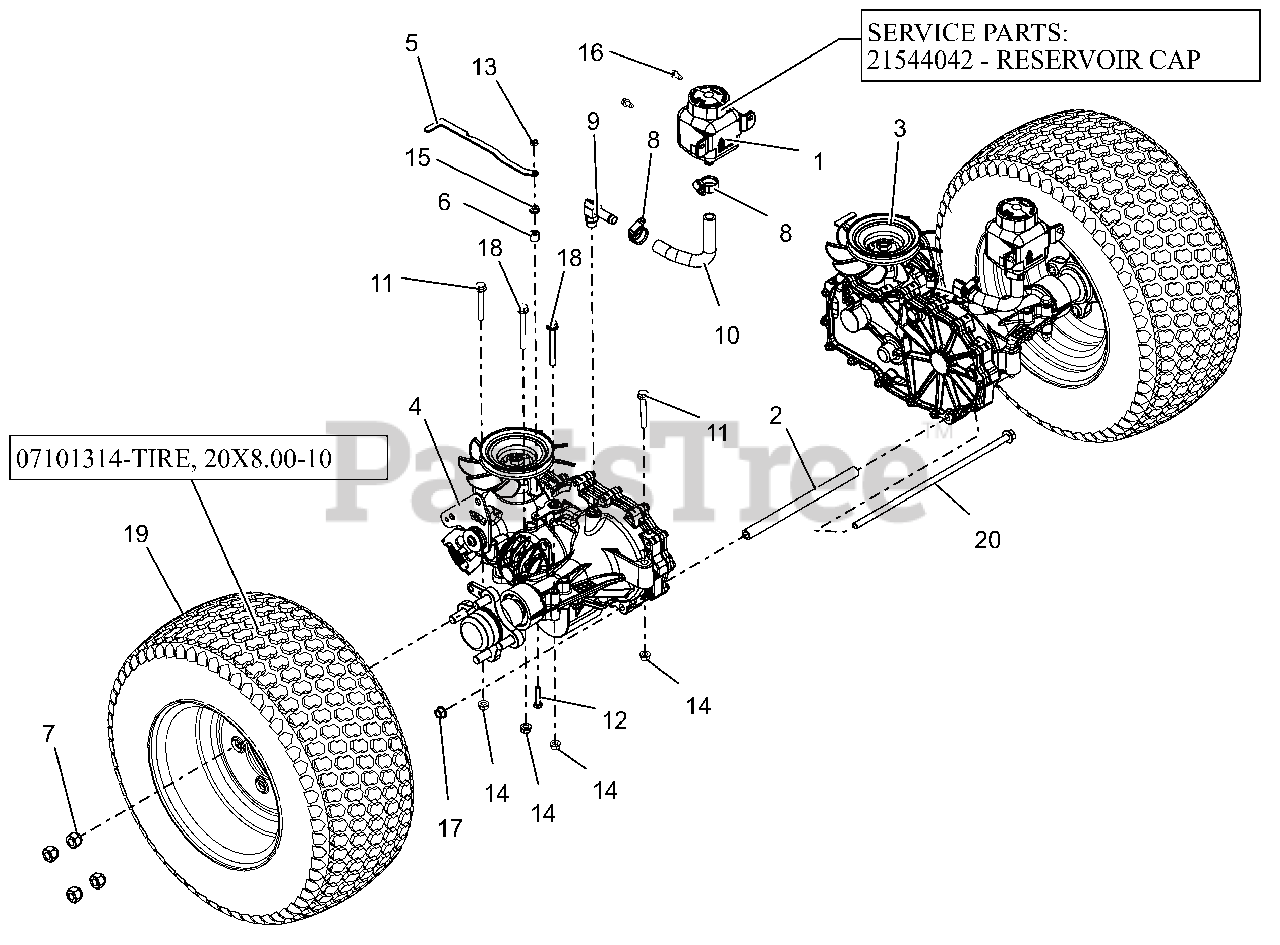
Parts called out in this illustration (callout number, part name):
1	TANK, EXPANSION
1	CAP, HYDRO RESERVOIR REPLAC.
2	SPCR, TRANSAXLE .406 ID X .630 OD X 9.27 (BLACK)
3	TRANSAXLE,ZT2800 LH
4	TRANSAXLE,ZT2800 RH
5	BRKT, DUMP VALVE
6	BSHG-SLV .265X.500X.500
7	NUT, WHEEL .50-20 ZCC
8	CLAMP,.88 DIA. HOSE
9	FITTING, HYD (90 DEG)
10	HOSE, FORMED LH XL
11	BLT,HEX-FLG .31-18X2.25 G5 ZCC
12	BLT, HEX .25-20X1.25 G5 ZCC
13	NUT-LK-CTR JAM .25-20 YWZC
14	NUT,LK-CTR-FLG .31-18 GF ZCC
15	NUT-SPNLK-FLG .25-20 ZC120
16	SCR-TAP .25-20X.50 HWH ZCC
17	NUT-LK-CTR-FLG .375-16 GF ZCC
18	BLT,HEX-FLG .31-18X2.75 G5 ZCC
19	ASSM TIRE\WHEEL, ASM
19	TIRE, 20X8.00-10 (MONITOR)
20	BLT, HEX-FLG 0.375-16X13 GR5 ZC120
